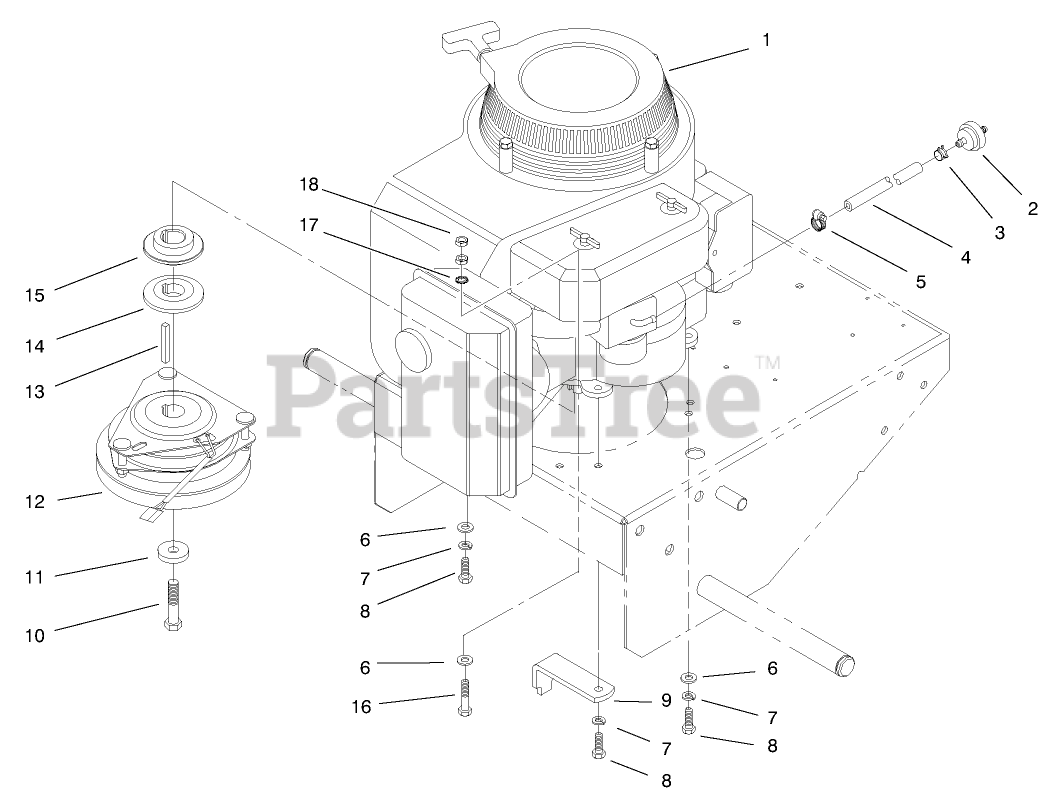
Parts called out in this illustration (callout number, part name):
1	Engine-12 Hp Kawasaki
2	FILTER-FUEL
3	CLAMP-HOSE
4	HOSE-FUEL
5	CLAMP-WORM
6	WASHER-PLAIN
7	WASHER-LOCK
8	SCREW-HH
9	RETAINER-CLUTCH
10	SCREW-CLUTCH
11	WASHER
12	CLUTCH/BRAKE
14	SHEAVE-LOWER HALF
15	SHEAVE-UPPER HALF
16	SCREW (ENGINE, GROUND)
17	WASHER-LOCK
18	NUT-JAM
